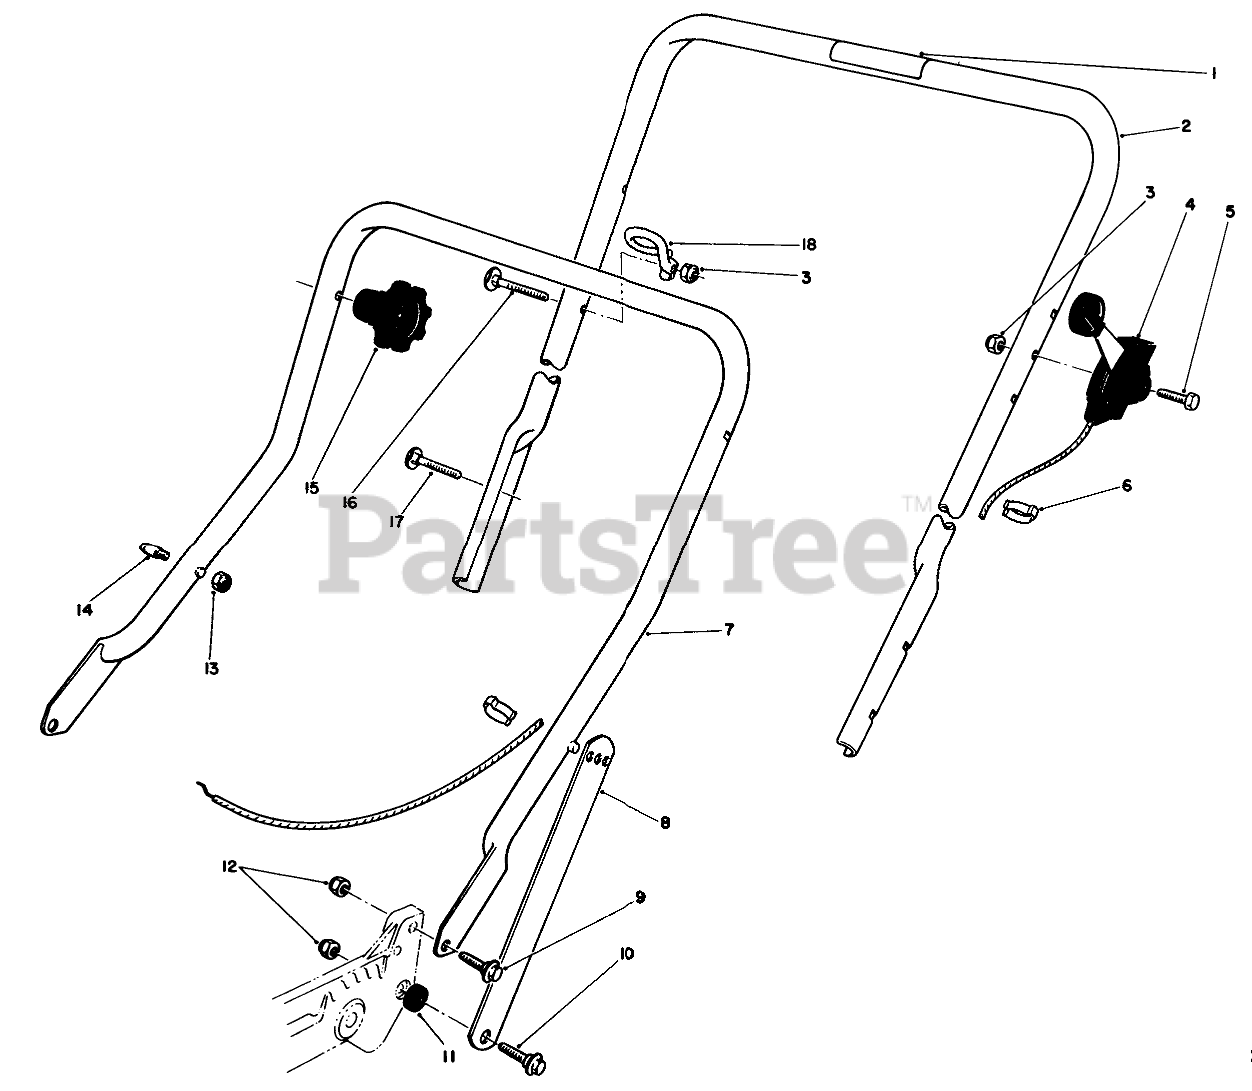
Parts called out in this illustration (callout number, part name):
1	DECAL - HANDLE
2	Handle-Upper (Incl. Ref. #1)
3	NUT-LOCK, NI
4	THROTTLE CONTROL - R&S
5	SCREW-HANDLE
6	BOWDEN CLIP
7	LOWER HANDLE ASM
8	Handle Latch
9	SCREW-SHOULDER
10	SCREW-SHOULDER
11	SPACER
12	NUT-LOCK, NI
13	NUT-LOCK, NI
14	HANDLE PIN
16	HANDLE SCREW
17	5/16-18 X 2 HNDLE SCREW
18	Guide
